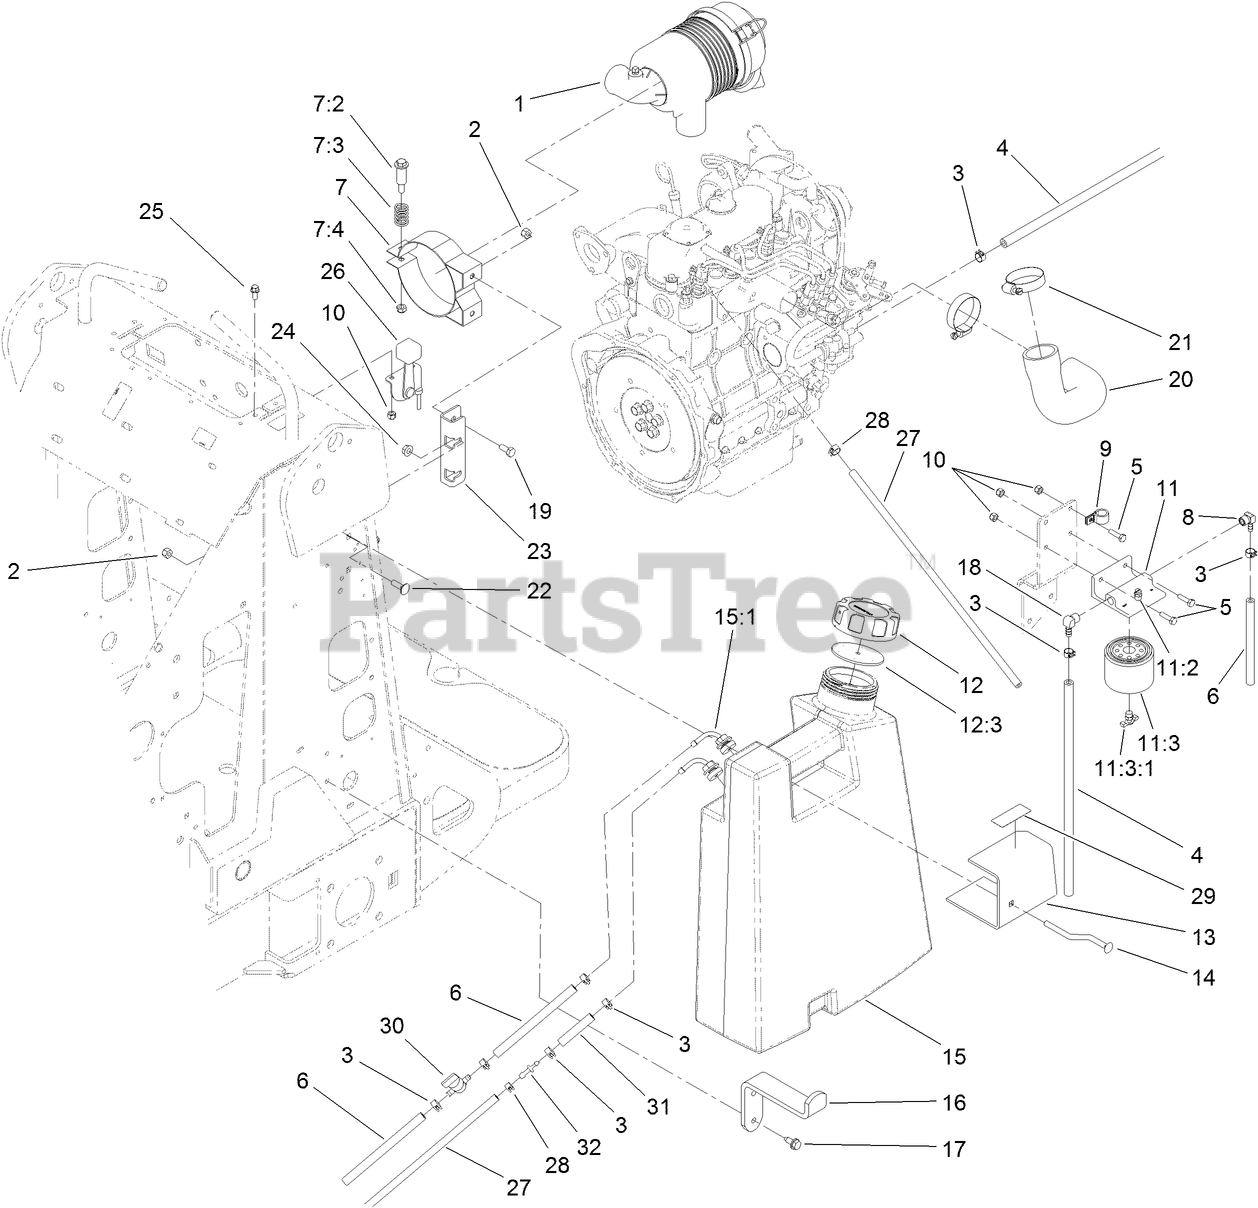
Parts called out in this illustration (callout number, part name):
1	AIR CLEANER ASM
2	NUT-LOCK, NI
3	CLAMP-HOSE
4	HOSE-FUEL
5	SCREW-HH
6	HOSE-FUEL
7	AIR CLEANER MOUNTING BAND ASM
7:3	SPRING
7:4	NUT
8	ELBOW
9	CLAMP-CABLE
10	NUT-LOCK, NI
11	FILTER HEAD ASM
11:2	VENT-AIR
11:3	ELEMENT-SPIN ON
11:3:1	VALVE-DRAIN
12	CAP-FUEL, DIESEL
12:3	GASKET-VENTED
13	PLATE-MOUNT, LEFT
14	BOLT-MOUNT
15	LH FUEL TANK ASM
15:1	FITTING-FUEL, BULKHEAD
16	MOUNT-BOTTOM, TANK
17	SCREW-HWHTF
18	FITTING-HYD, 90
19	SCREW-HH
20	HOSE-CLEANER, AIR
21	CLAMP-HOSE
22	BOLT-CARR
23	MOUNT-CLEANER, AIR
24	NUT-HF
25	SCREW-HHF
26	CONTROL-THROTTLE
27	HOSE-FUEL
28	CLAMP-HOSE
29	DECAL-LOW SULFUR
30	VALVE-FUEL
31	HOSE-FUEL
32	FITTING-STRAIGHT
